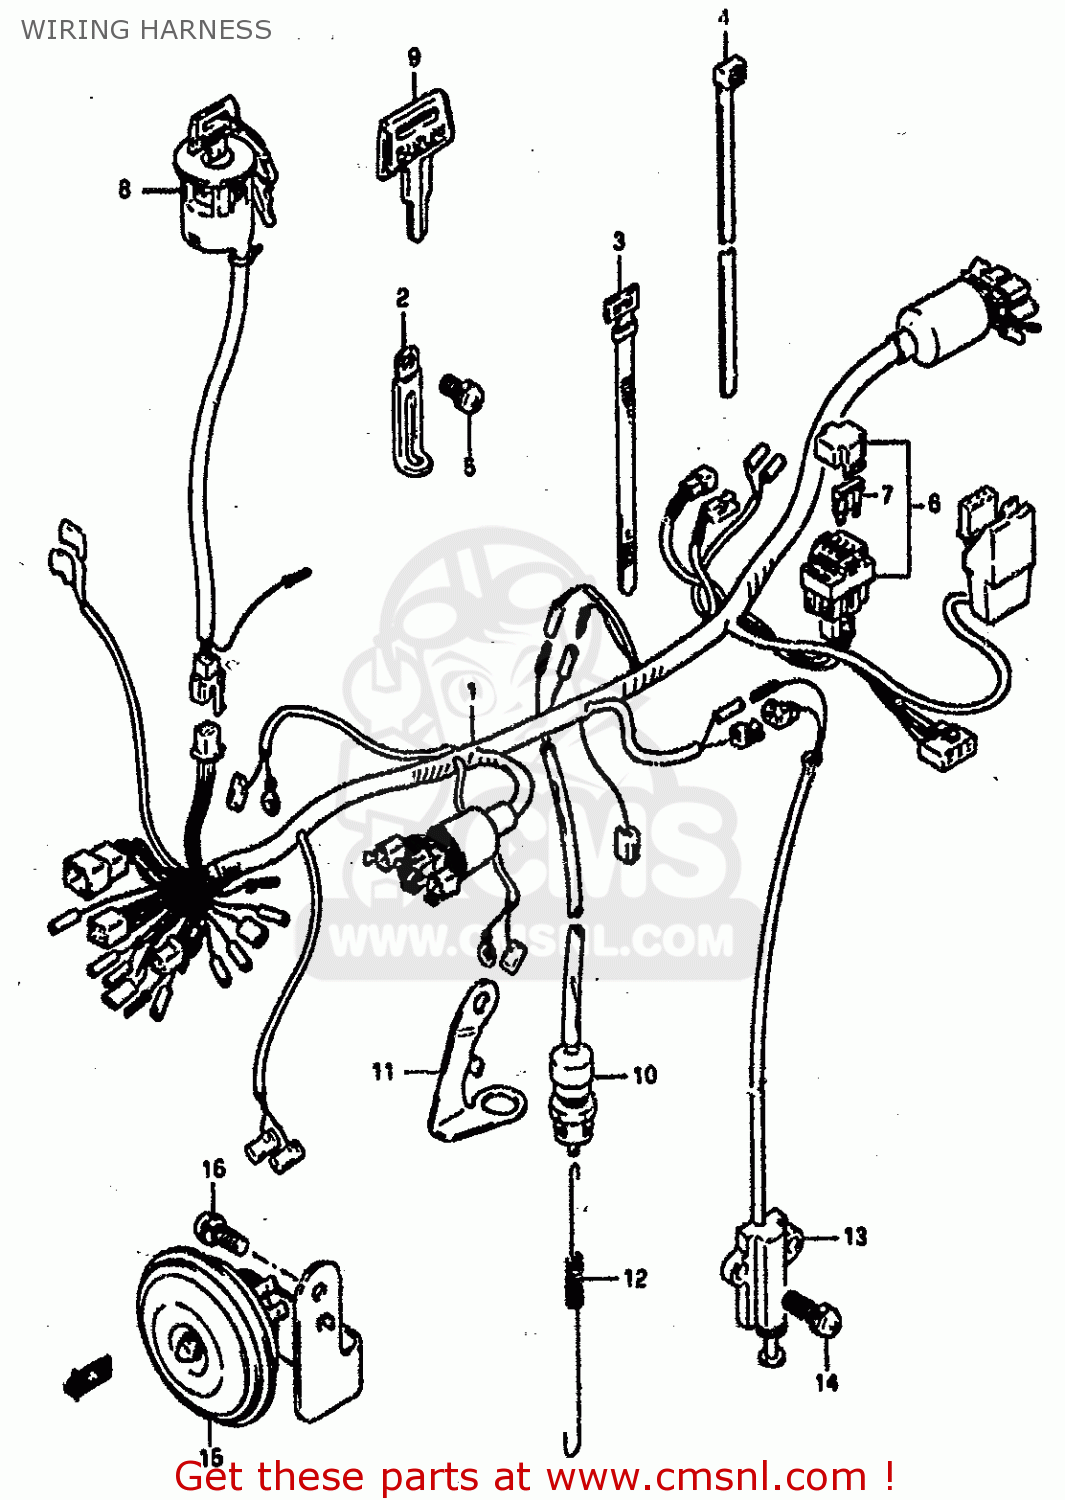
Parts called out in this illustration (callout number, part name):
1	HARNESS,WIRING
2	CLAMP
3	CLAMP(L:125)
4	CLAMP(L:300)
5	SCREW
6	BOX ASSY,FUSE
7	FUSE(15A)
8	SWITCH ASSY,IGNITION
9	KEY,BLANK
10	SWITCH ASSEMBLY,STOP LAMP
11	BRACKET (WHITE)
12	SPRING
13	SWITCH ASSEMBLY,SIDE STAND
14	SCREW
15	HORN ASSEMBLY
16	SCREW
